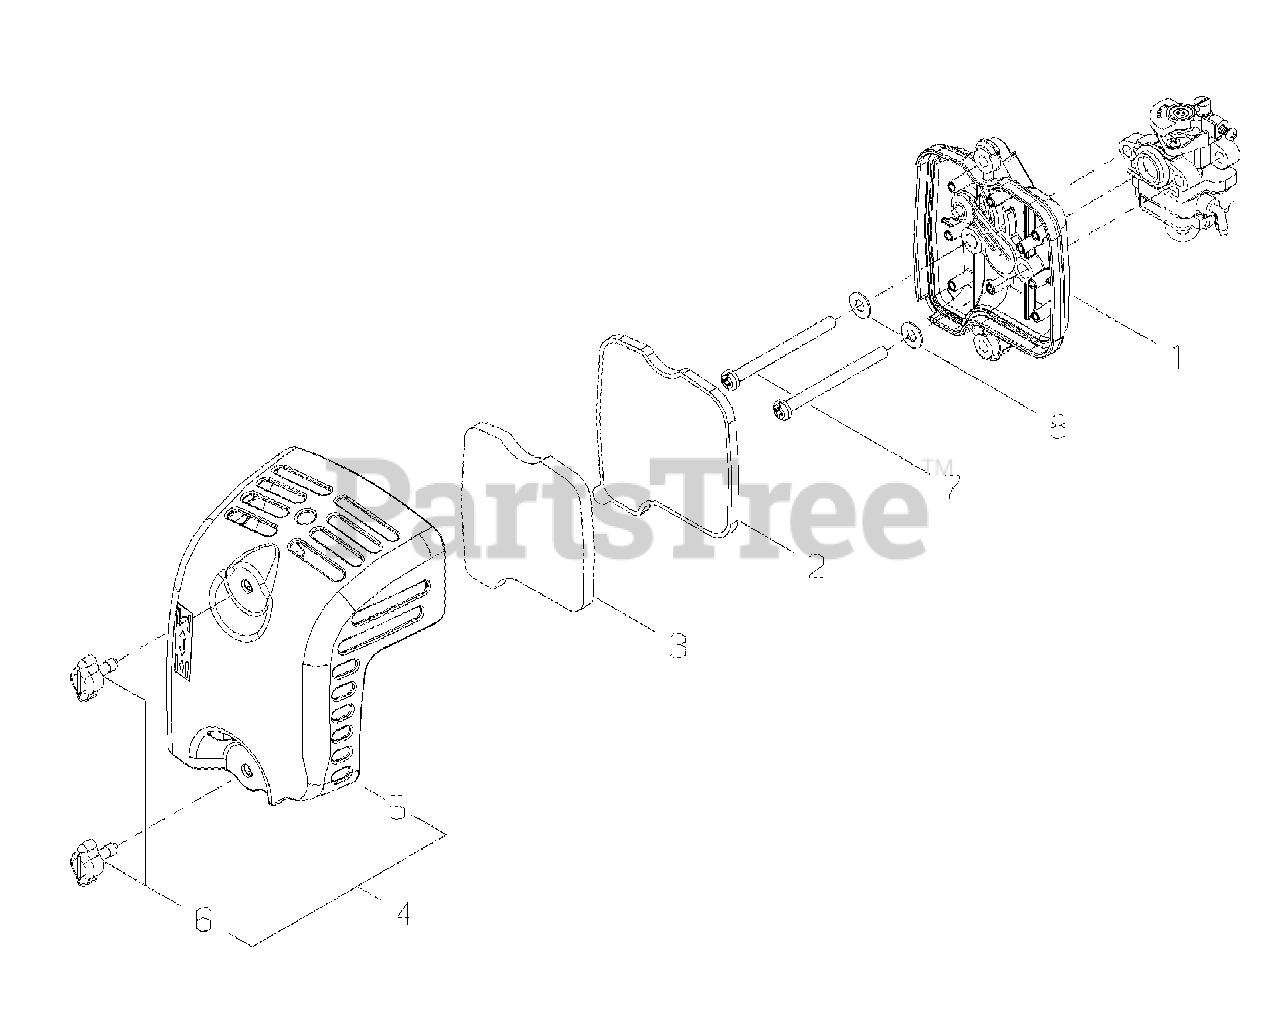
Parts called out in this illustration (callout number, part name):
1	AIR FILTER CASE ASSY
2	FILTER, AIR
3	PRE-FILTER - FOAM
4	AIR FILTER COVER ASSY
5	COVER, AIR FILTER
6	THUMBSCREW
7	SCREW - 5X60
8	WASHER - 5
